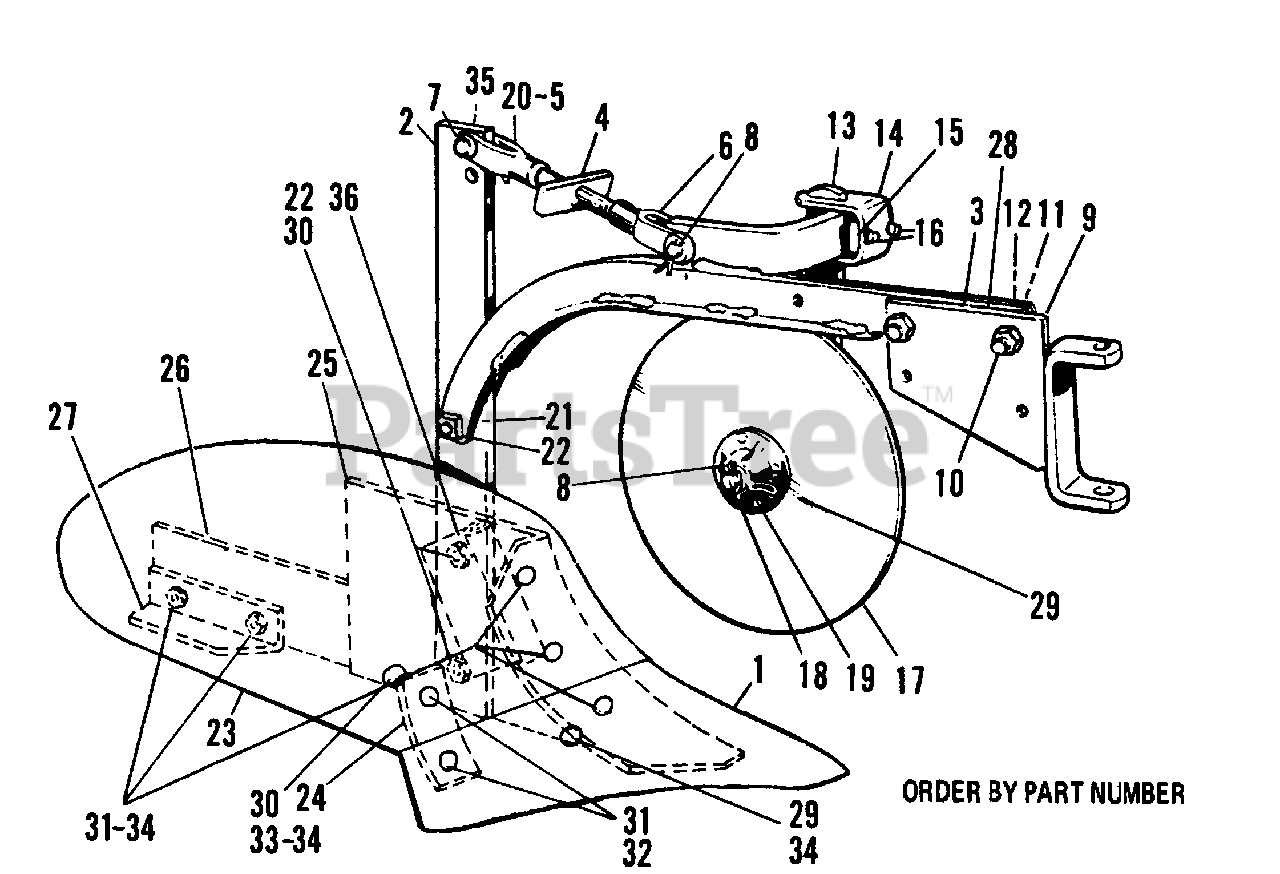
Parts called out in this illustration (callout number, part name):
3	Beam Assembly, Plow
4	Yoke Rod Assembly
5	Yoke, Left Hand
6	Yoke, Right Hand
7	Pin, Yoke
8	Pin, Cotter, w/extended prong, 1/8" dia. x 1" lg.
9	End Assembly, Flow Beam
10	Capscrew, Hex Hd., 3/8"-16 x 2-1/4" lg.
11	Lockwasher, 3/8"
12	Nut, Full Hex, 3/8"-16 NC
13	Standard, Coulter
15	Nut, Special, 5/16" x 1" x 2-1/4" lg.
16	Set Screw, Cup Point, Sq. Hd., 3/8"-16 NC x 1" lg.
17	Coulter Assembly, w/bushing
18	Spindle, Coulter
20	Jam Nut, Hex, 5/8"-11 NC
21	Hex Capscrew, 1/2"-13 NC x 1-3/4" lg.
22	Nut, Full Hex, 1/2"-13 NC
23	Moldboard
24	Brace, Moldboard
27	Angle, Slip heel
28	Spacer, Plow Beam
29	Bushing, Coulter
30	Plow Bolt
31	Plow Bolt
33	Lockwasher, 1/2"
34	Nut, 7/16"-14
35	Safety Clip, Pin
36	Support Assembly
